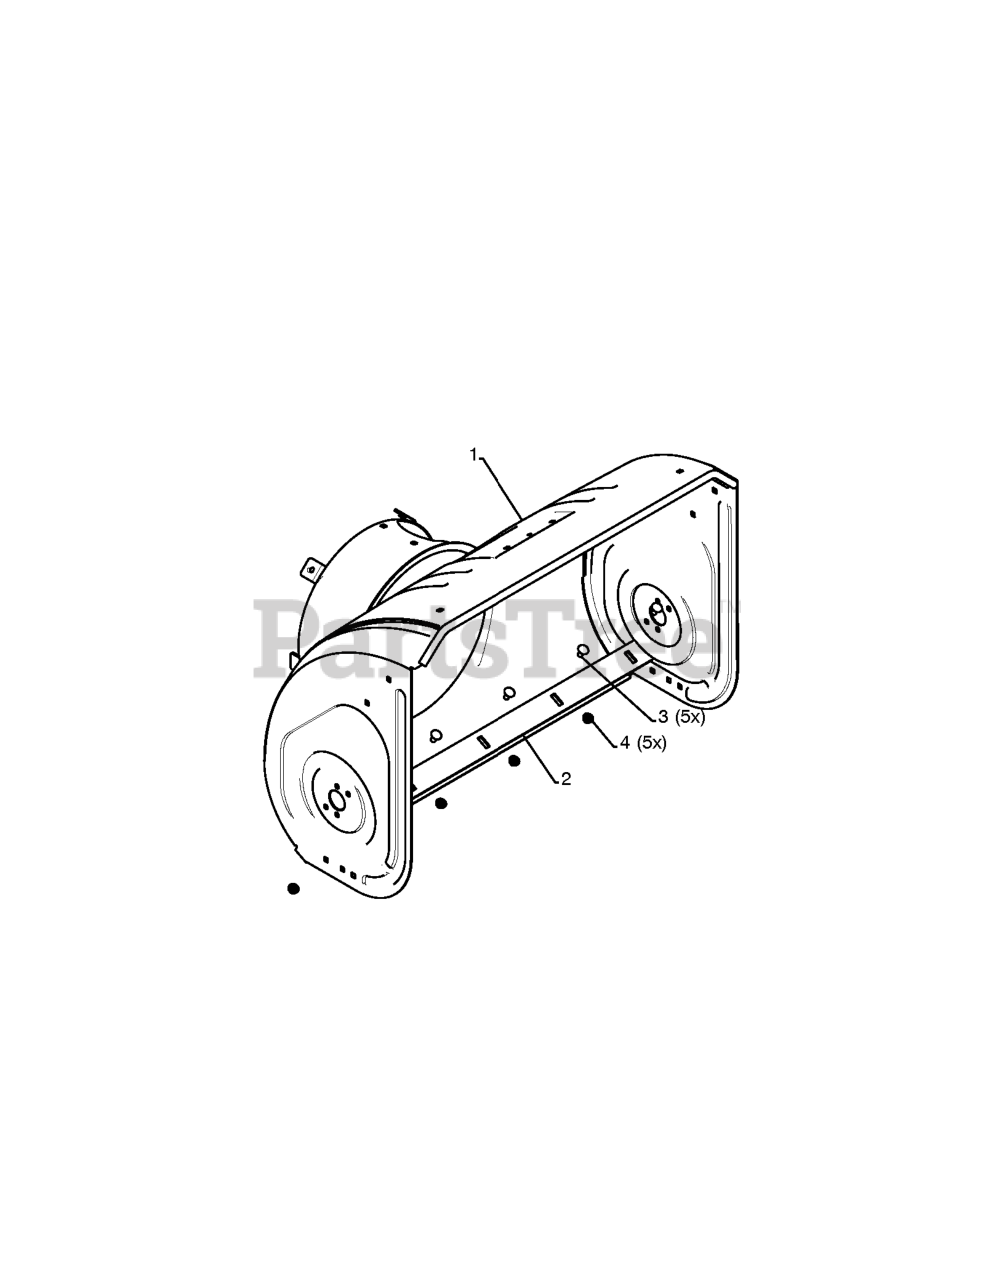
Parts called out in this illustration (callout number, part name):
1	HOUSING.AUG.WELDMENT.30.ORANGE
2	BAR, SCRAPER
3	BOLT
4	NUT.FLANGE.5/16
